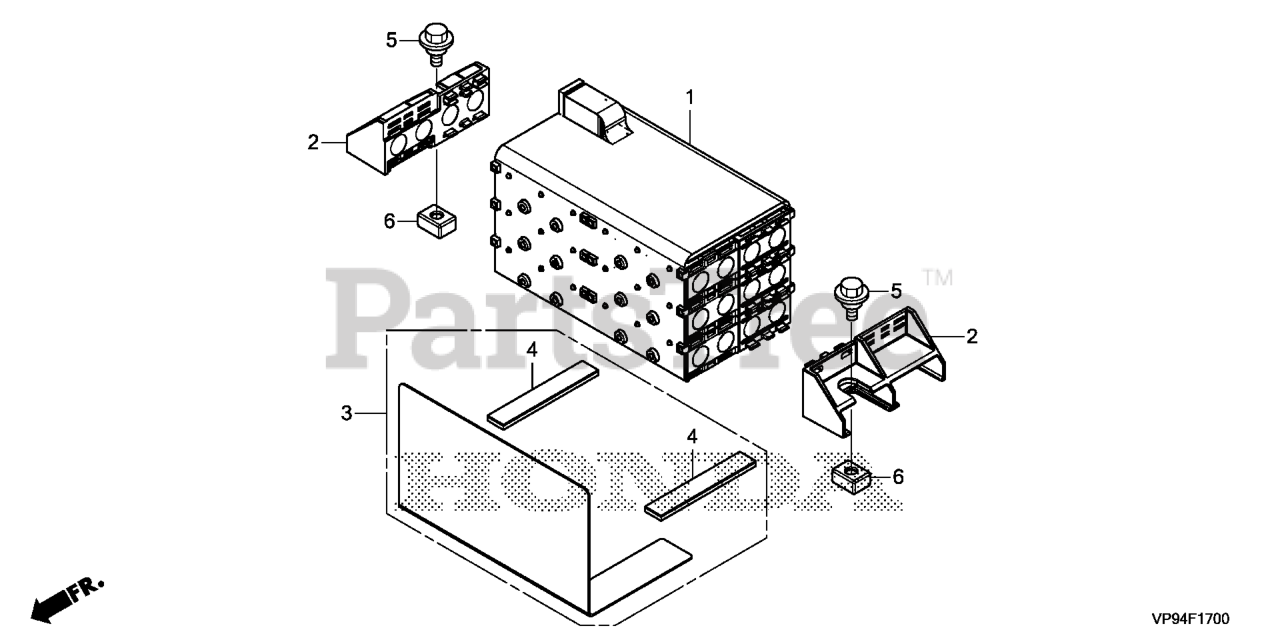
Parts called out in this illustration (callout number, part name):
1	BATTERY ASSY. (6S3P)
2	PLATE, BATTERY SETTING
3	PLATE, BATTERY
4	MAT B, SPLASH GUARD
5	BOLT, FLANGE (6MM)
6	NUT, SPECIAL (6MM)
